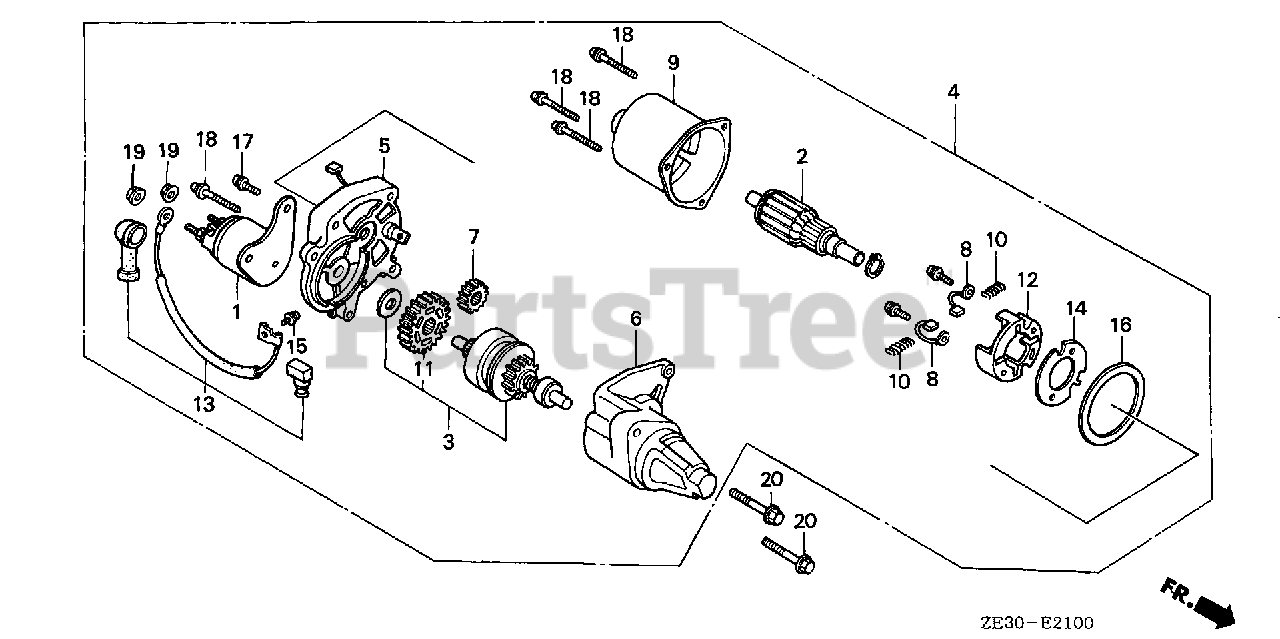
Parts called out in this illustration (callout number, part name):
1	CONTACTOR ASSY.
2	ARMATURE
3	CLUTCH, OVERRUNNING
4	STARTER MOTOR UNIT
5	BRACKET, CENTER
6	BRACKET, FR.
7	GEAR, DRIVE PINION
8	BRUSH
9	YOKE
10	SPRING, BRUSH RETURN
11	GEAR, REDUCTION
12	HOLDER, BRUSH
13	WIRE, WATER COVER
14	INSULATOR
15	SCREW-WASHER (4X6)
16	GASKET
17	SCREW-WASHER (5X14)
18	SCREW-WASHER (5X32)
19	NUT-WASHER (6MM)
20	BOLT, FLANGE (8X35)
